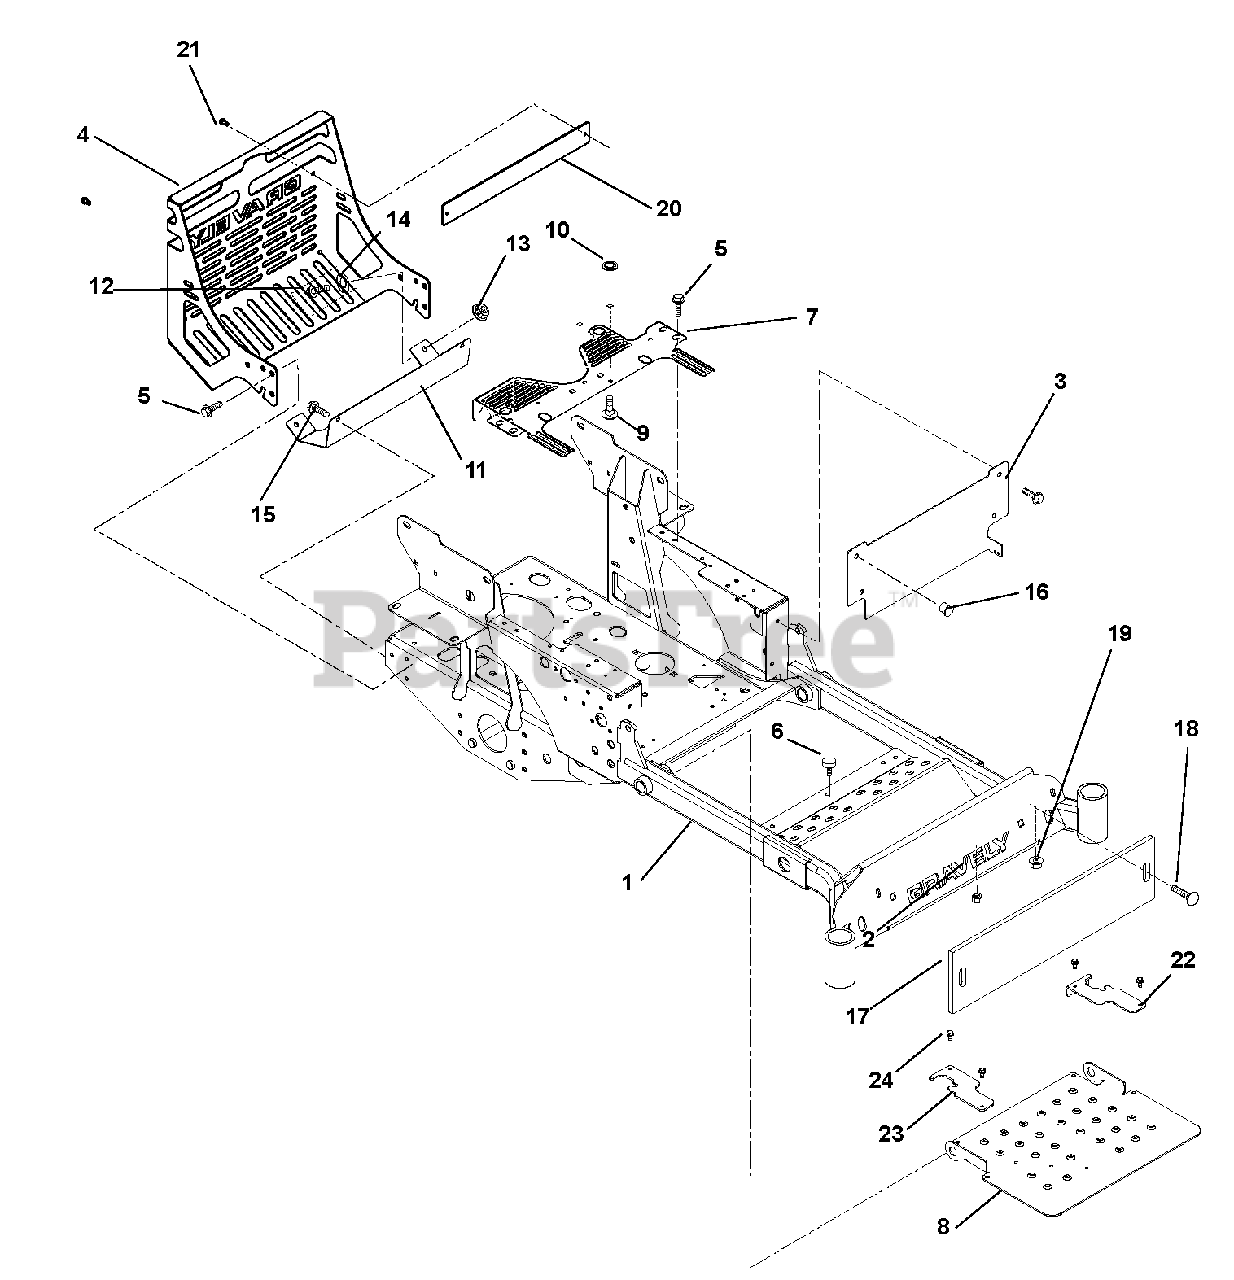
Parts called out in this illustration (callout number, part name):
1	Frame, Compact-Z
2	Nut, Spin Lock Flange .312-18
3	Access Panel, CE
4	Bumper, Rear
5	Screw, Tapping .38-16 x .75 Hex Washer Head
6	Bumper, Rubber
7	Seat Support
8	Panel, Inspection
9	Bolt, Round Head Square Short Neck .31-18 x .75
10	Nut, Push .312
11	Heat Shield, Compact Z
12	Bolt, Hex .38-16 x .75
13	Nut, Nyloc Flange .38-16
14	Washer, Flat Steel .438 x 1.00 x .083
15	Screw, Tapping .38-16 x .50 Hex Washer Head
16	Plug, Hole .56
17	Counterwieght CZ Front - Black
18	Bolt, Round Head Square Neck .50-13 x 2.50
19	Nut .50-13 Nyloc Flange
20	Plate, Bumper
21	Screw, Tapping .25-20 x .50 Hex Washer Head
22	Bracket, Mounting Right Hand
23	Bracket, Mounting Left Hand
24	Screw, Tapping .25-20 x .50 Hex Washer Head
